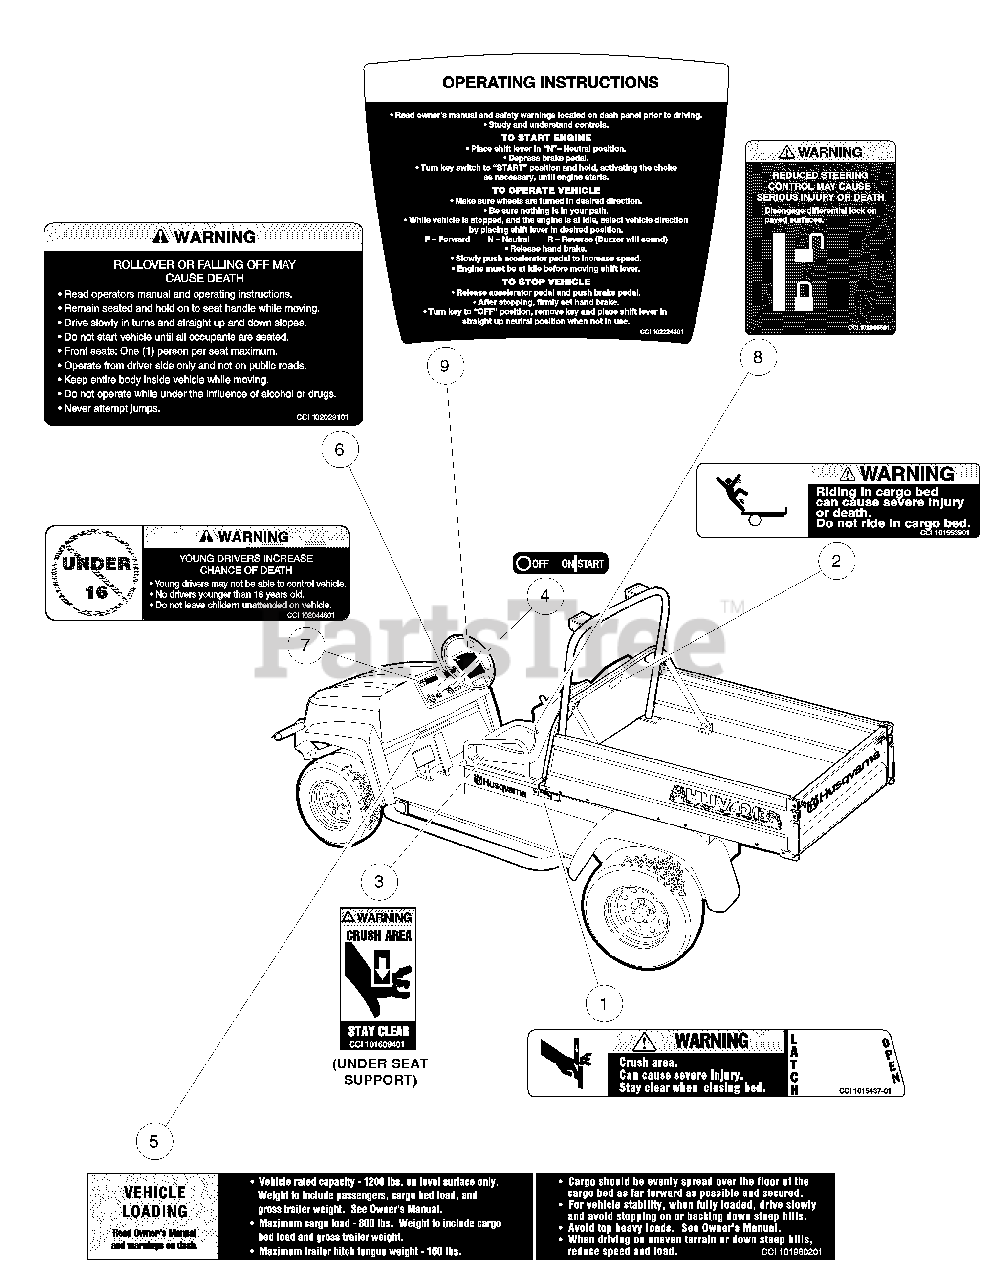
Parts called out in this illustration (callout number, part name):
1	Decal, Tilt Bed Warning
2	Decal, Bed Load Warning
3	Decal, Crush Area Warning
4	Decal, Off/On/Start
5	Decal, Vehicle Loading
6	Decal, Dash Warning
7	Underage Warning Decal
8	Decal, Differential Lock Warning
9	Decal, Operating Instructions
